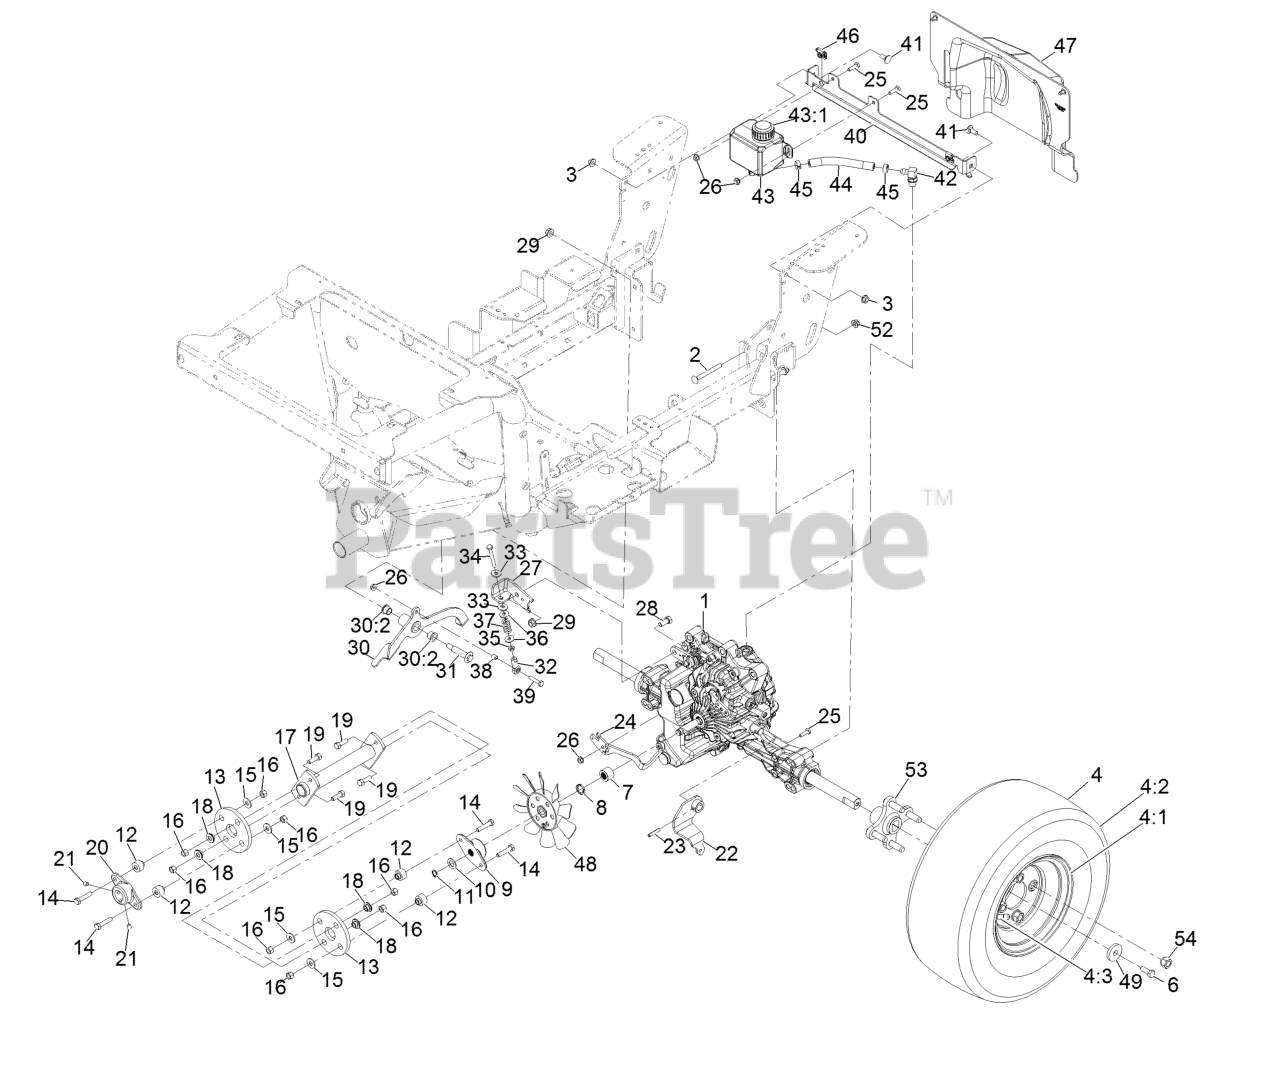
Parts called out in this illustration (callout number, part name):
1	Transaxle
2	Screw-CARR
3	Nut-Hex Flg
4	Wheel And Tire
4:1	ASM(18X7.5-8) White Tire-4 Ply
4:2	Wheel, 8 X 5.375
4:3	Stem-Valve
6	Screw-HH
7	Spacer-Shaft, Input
8	Washer-Spring
9	Hub-Shaft, Transaxle
10	Spacer
11	Ring-Retaining
12	Spacer-Coupling, Rubber
13	Coupling-Rubber
14	Screw-HH 5/16-24 X 1 1/2
15	Washer-5/16 Std
16	Nut-Hex 5/16-24
17	Shaft-Drive
18	Spacer-Coupler, Rubber
19	Screw-HH
20	Hub-Shaft, Engine
21	Setscrew-5/16-18 X 3/8
22	Arm-Motion
23	Pin-Spiral
24	Arm-Release
25	Screw-HH 1/4-20 X 7/8 SS
26	Nut-Hex Flg
27	Arm-Brake
28	Screw-HH
29	Nut-Hex Flg
30	Brake Lever ASM
30:2	Bearing-Flange
31	Bolt-Shoulder
32	Rod End-Ball Joint
33	Washer-Spring Disc 5/16
34	Screw-HH
35	Nut-Jam 1/4-28
37	Spring-Compression
38	Spacer
39	Screw-HH 1/4-20 X 1 1/4
40	Bracket-Mount, Tank
41	Screw-CARR
42	Fitting-90 DEG
43	Tank ASM
43:1	Cap-Tank
44	Hose-Expansion
46	Receptacle-Clip, Mini
47	Transaxle Cover ASM
48	Fan-7 Inch
52	Nut-Nyloc 5/16-18 Flg
53	ASM-Wheel Hub
54	Nut-Lug 1/2-20
